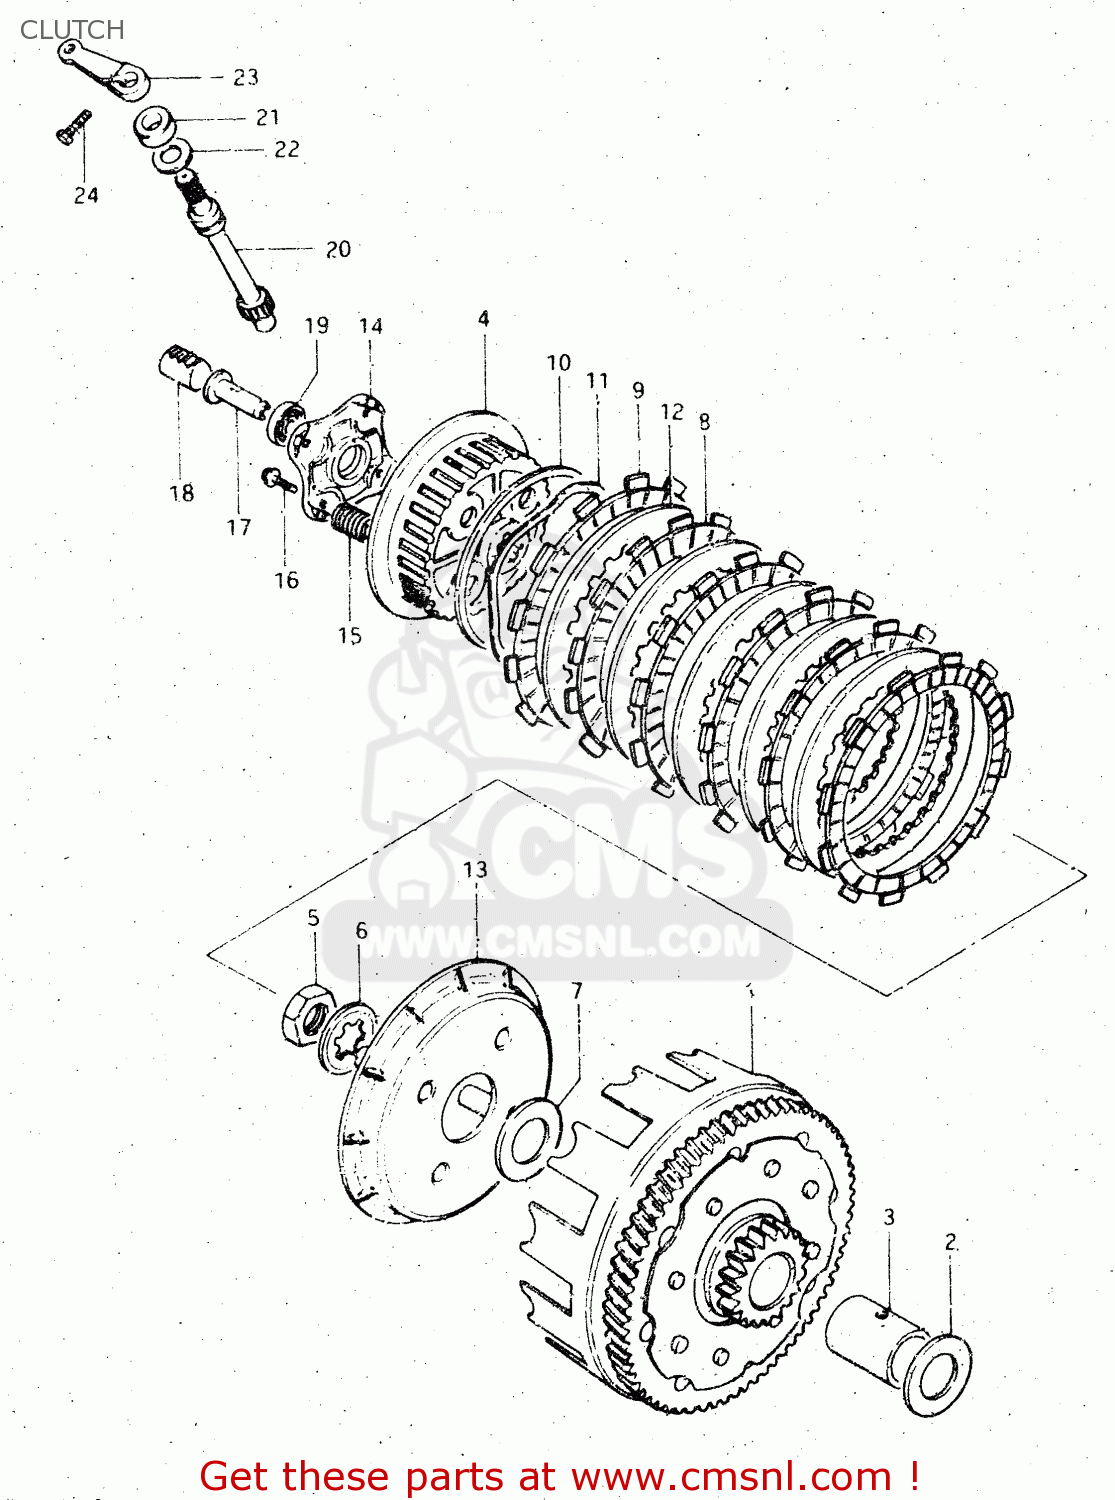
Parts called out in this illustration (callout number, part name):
1	GEAR ASSEMBLY,PRIMARY DRIVE
2	WASHER
3	SPACER(22X28X32.5)
4	HUB,CLUTCH SLEEVE
5	NUT
6	WASHER,LOCK
7	WASHER
8	PLATE,CLUTCH DRIVE (NAS)
9	PLATE,CLUTCH DRIVE
10	SEAT,WAVE WASHER(T:1.4)
11	WASHER
12	PLATE,CLUTCH DRIVEN
13	DISC,CLUTCH PRESSURE
14	PLATE,RELEASE
15	SPRING
16	BOLT,REAR
17	PIECE,CLUTCH PUSH
18	RACK,CLUTCH RELEASE
19	BEARING
20	PINION,CLUTCH RELEASE
21	OIL SEAL
22	WASHER (14.2X22X1)
23	ARM,CLUTCH RELEASE
24	BOLT
